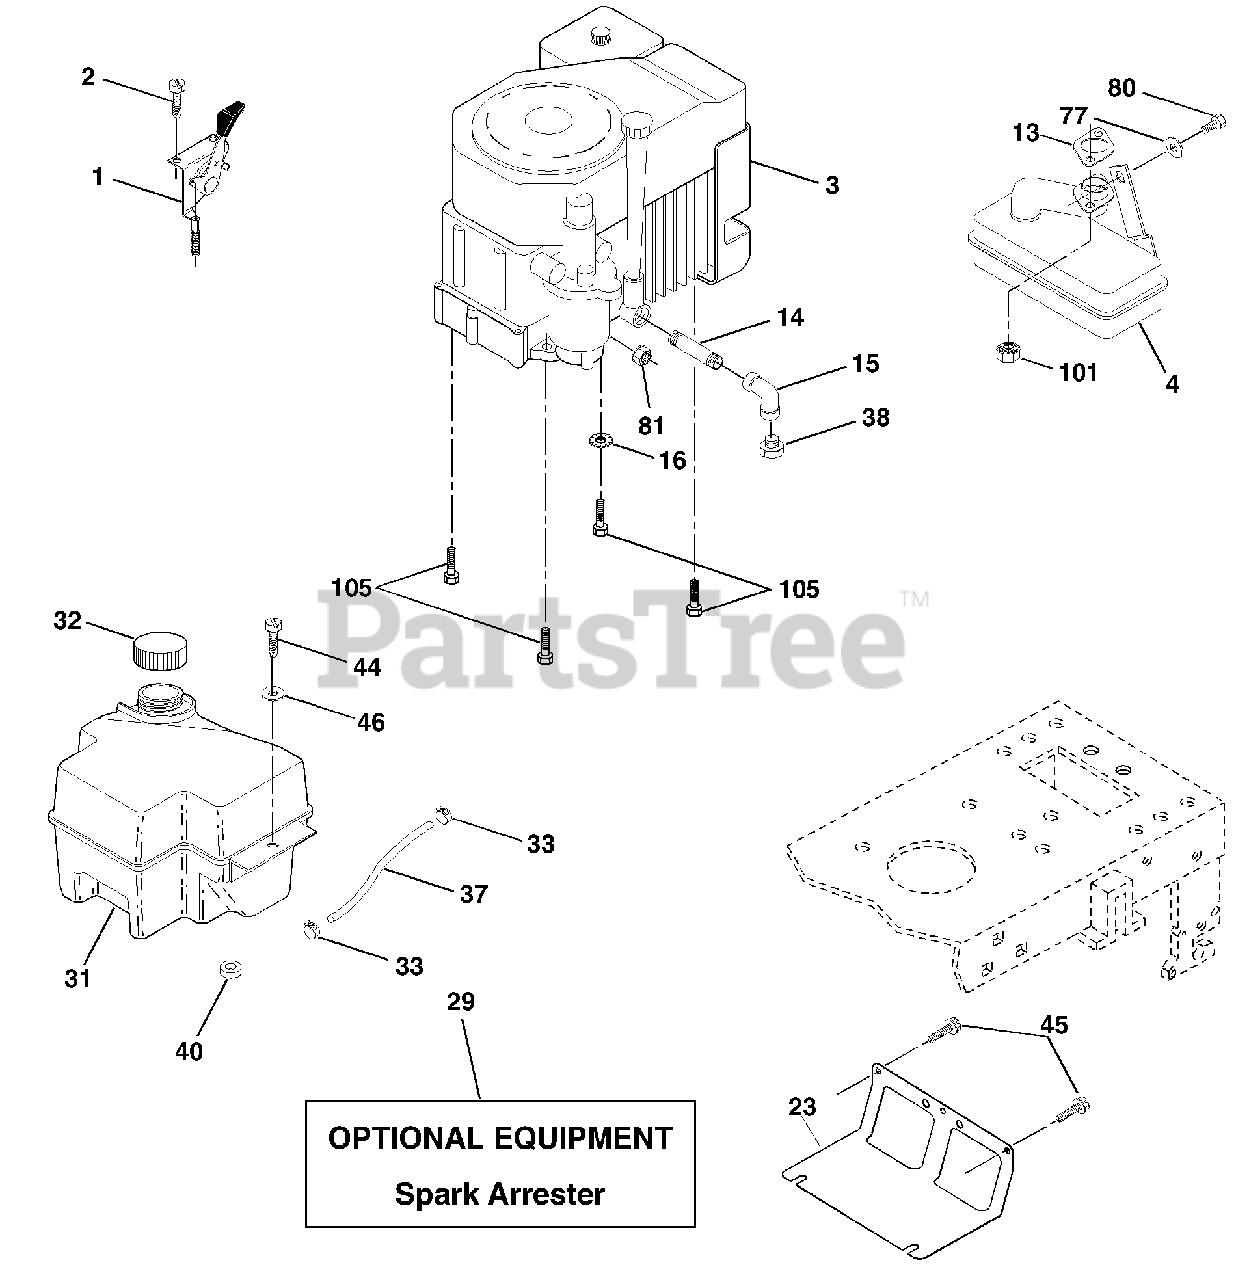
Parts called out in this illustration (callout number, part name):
1	Control Th/ch 27 LH Flag
2	Screw Hex Thd Cut 1/4-20 x 5/8 T
4	Muffler
14	Nipple Pipe
15	Elbow Std 90 Degree 3/8-18 Npt
16	Washer Lock Ext Tooth 3/8
23	Shield Brn/Dbr Guard
29	Kit Spark Arrestor (Flat Scrn)
31	Tank Fuel Front 2 00
32	Cap Asm Fuel W/sym Vented
33	Clamp Hose Black
37	Line Fuel 20"
38	Plug Oil Drain
40	Bushing Snap Nyl Blk Fuel Line
44	Screw Hexwsh Thdrol 1/4-20x3/4
45	Screw
46	Washer 9/32 X 7/8 X 16 Ga
77	Washer 5/16 x 3/4 x 16 Ga.
80	Bolt Hex Hd 5/16-18 x 1/2
81	Nut Flange 1/4-20 Starter Nut
101	Nut Flange M8-1.25
105	Screw 3/8-16 x 1
